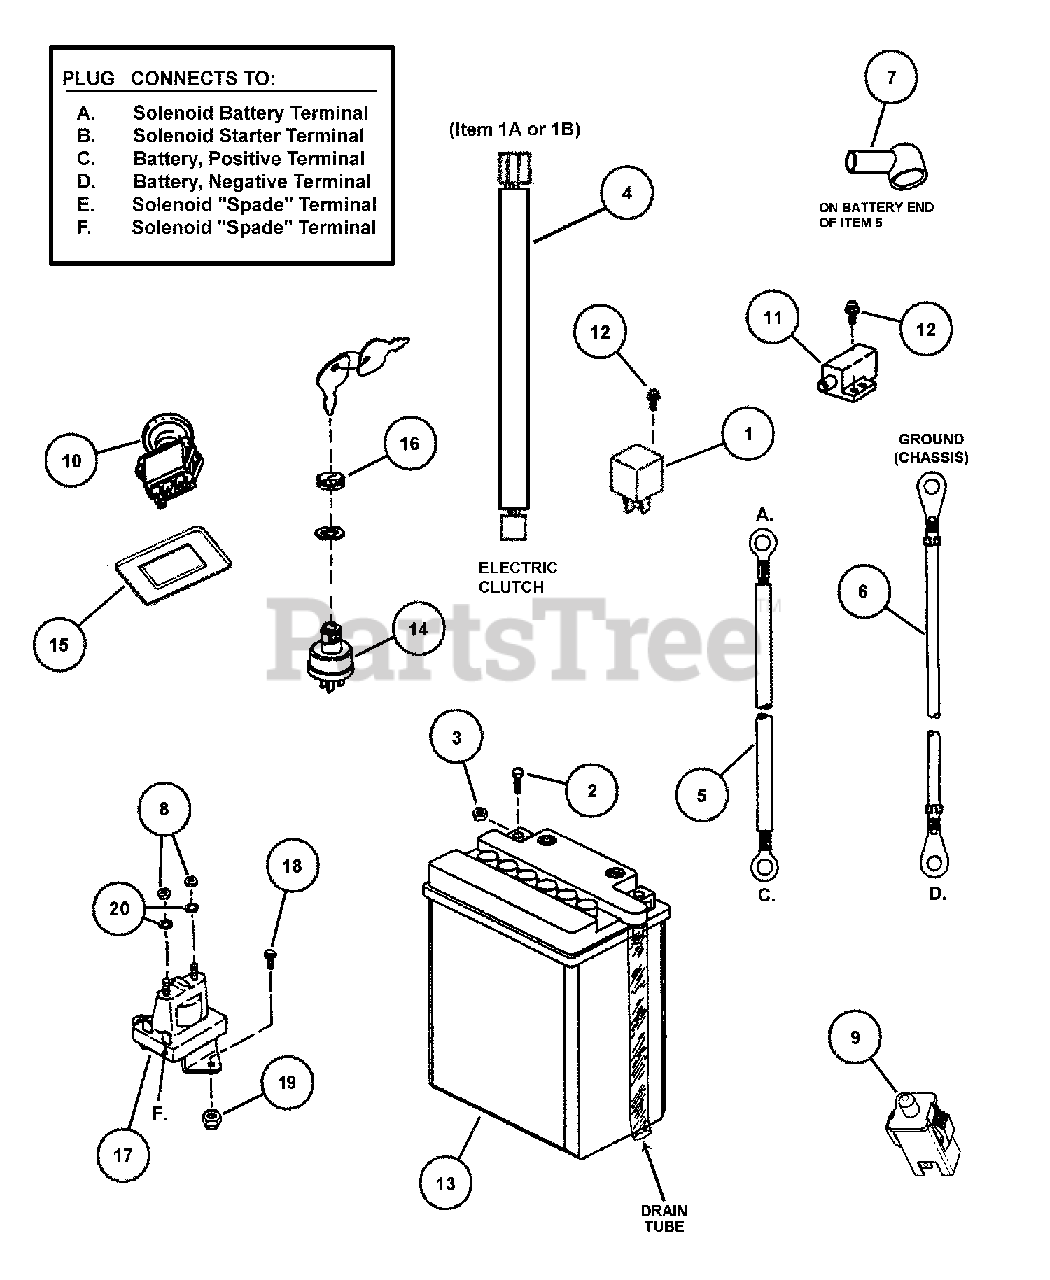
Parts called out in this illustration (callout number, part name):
1	RELAY, OPC, Electric Clutch
2	SCREW, #10-24 x 1/2" Hex Head Cap
3	NUT, #10-24 Hex Twin "Whiz" Lock
4	WIRE HARNESS, Warner Clutch
5	WIRE, Positive, 13" long
6	WIRE, Negative, 14" long
7	COVER, Battery Cable
8	NUT, 1/4-20 Hex Jam, GR 5 or B
9	SWITCH, Seat (NO/NC) Snap-In
10	SWITCH, PTO E.C.
11	SWITCH, Park Brake (NC/NO)
12	SCREW, #10-24 x 1/2" Hex Washer Self-Tap (Torx)
13	BATTERY, 12V, 3 Amp, 190 Cold Cranking Amp
14	SWITCH, Ignition (After-fire Solenoid)
16	BEZEL
17	SOLENOID - Super Trombetta- 2 Terminal
18	SCREW, 1/4-20 x 1/2" Hex Head Cap, GR 5
19	NUT, 1/4-20 Hex Flange Lock
20	WASHER, 1/4" Internal Tooth Lock
